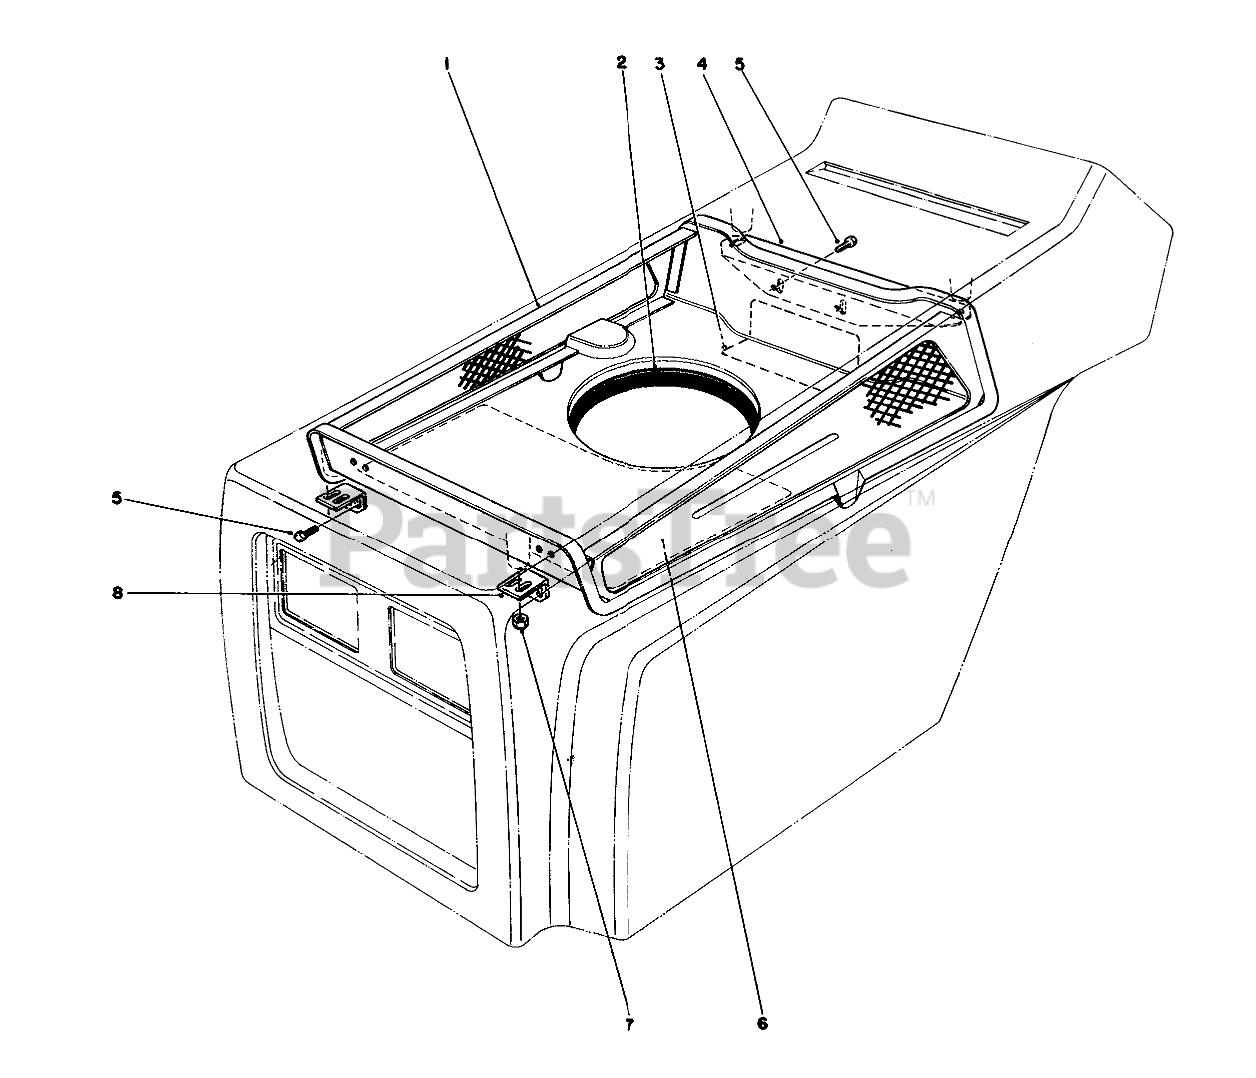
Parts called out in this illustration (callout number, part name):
1	Duct Hood
2	Seal Engine
3	BELT DECAL
4	Bracket Rear Duct Support
5	SCREW-HWHTF
6	Decal Service
7	NUT-LOCK, NI
8	Bracket Front Duct Support
